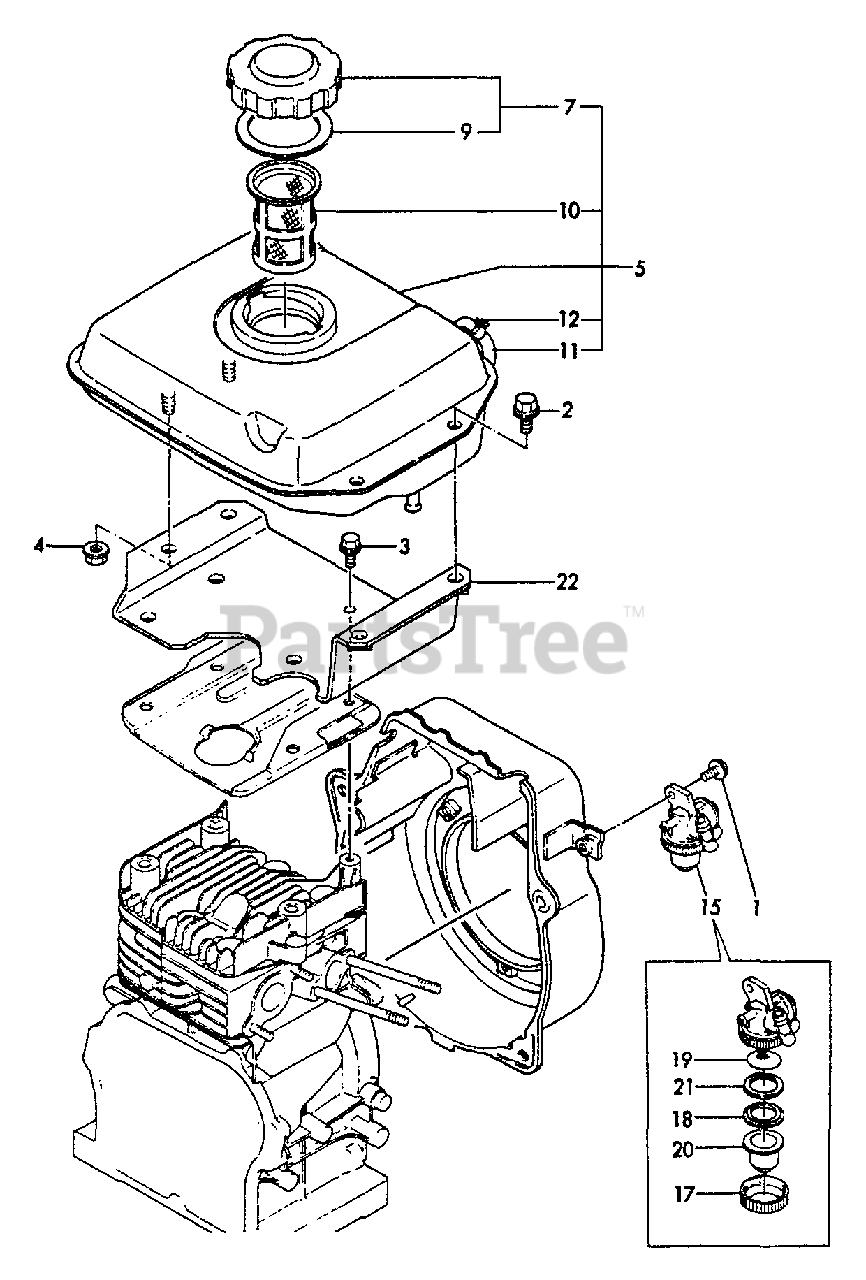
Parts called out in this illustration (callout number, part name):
1	BOLT - 6×12 -- PLATED
2	BOLT - 8×14 -- PLATED
3	BOLT - 6×8 -- PLATED
4	U-NUT M8
5	FUEL TANK ASSY
7	CAP ASSY
9	GASKET
10	STRAINER, FUEL
11	GAUGE, LEVEL
12	CLAMP, HOSE - 9
15	COCK ASSY, FUEL
17	RETAINER
18	GASKET
19	FILTER, FUEL
20	BOWL, STRAINER
21	PLATE
22	BRACKET, FUEL TANK
